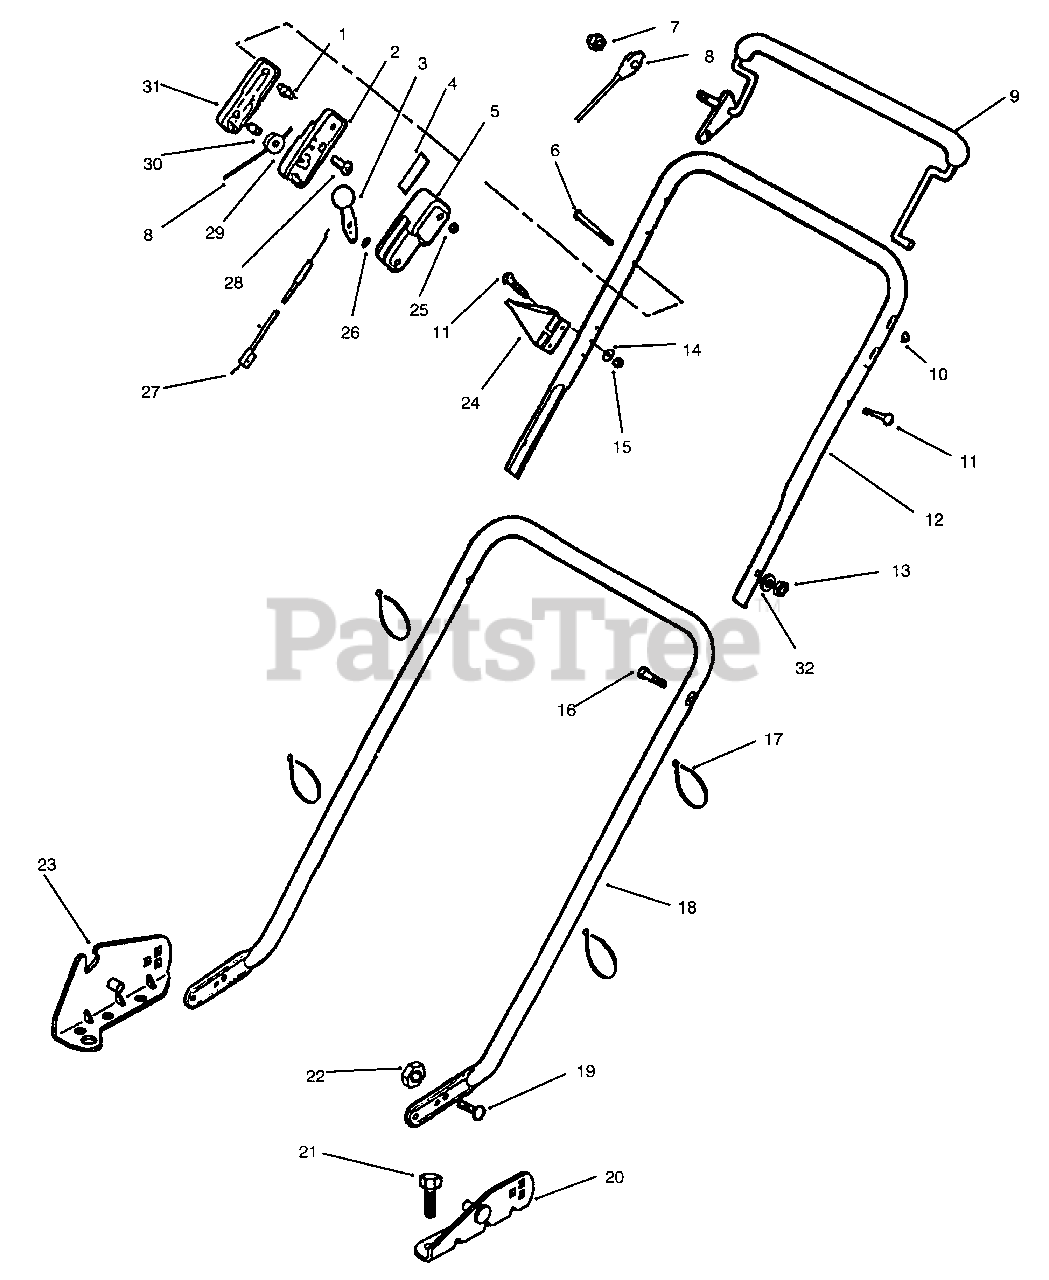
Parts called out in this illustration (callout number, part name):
2	Case-Throttle, Center
3	Assembly-Knob & Lever
4	Decal-Control, Throttle
5	Case-Throttle, Inner
7	Nut-Acorn
8	Cable-Throttle
9	Assembly-Lever, Control
10	Palnut
12	Handle-Top
13	Nut-Handle
17	Strap-Tie
18	Handle-Lower
19	Bolt
20	Bracket-Handle, L.H.
23	Bracket-Handle, R.H.
24	Assembly-Guide, Rope
27	Cable-Throttle
30	Pin-Pulley
31	Case-Throttle, Outer
32	Washer-Screw, Handle
